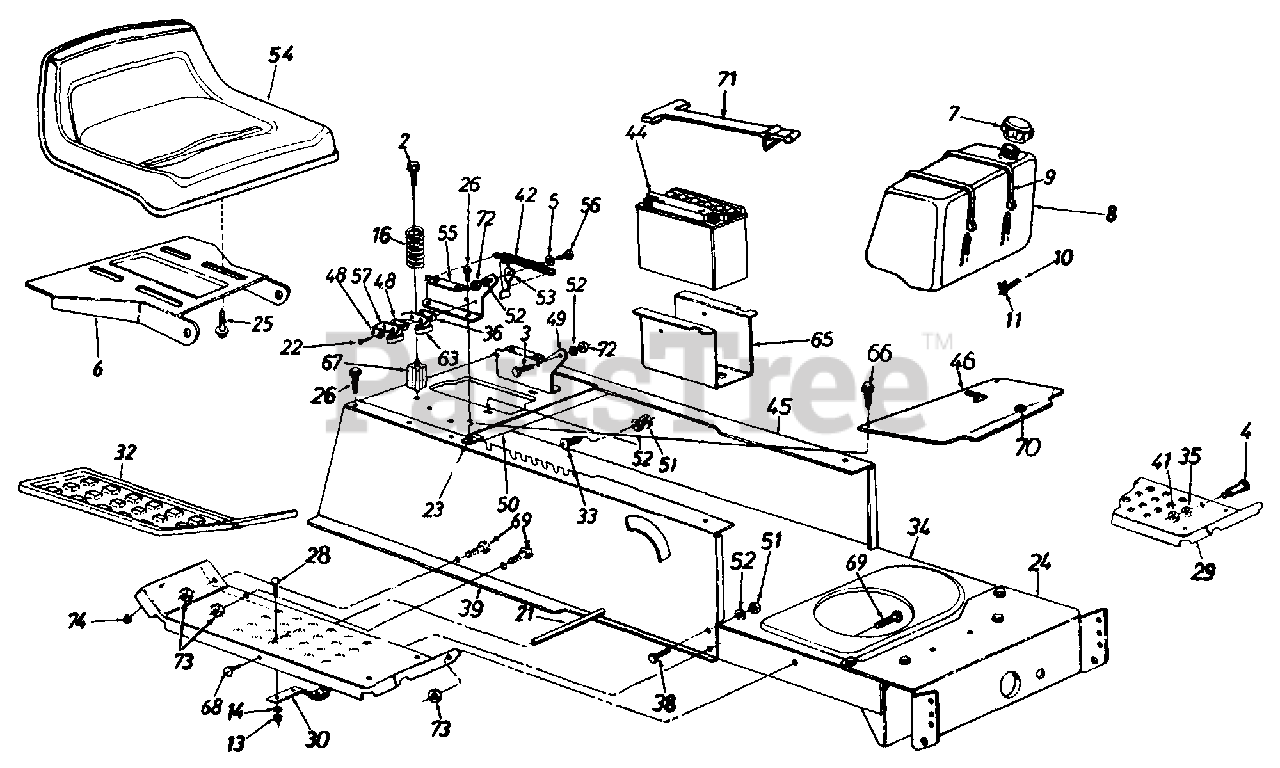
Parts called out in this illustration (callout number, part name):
2	Hex Wash. Hd. Tap Scr. 5/16-18 x 3.25" Lg.
3	Shld. Bolt .437" Dia. x .162"
5	Spr-Wash. .445" I.D. x .75
7	Fuel Cap
9	Tie Strap
10	Fuel Line
13	Hex Nut 1/4-20 Thd.
14	L-Wash. 1/4" I.D.
16	Compression Spring
21	Running Board Rod
22	Hex Hd. AB-Tap Scr. #8 x .50"
23	Speed Nut #10Z
25	Hex Tap Scr. 3/8-16 x .62" Lg.
26	Hex Wash. Hd. AB-Tap Scr. 5/16 x .75" Lg.
32	Rubber Foot Pad - L.H.
33	Truss Mach. Scr. 5/16-18 x .75" Lg.
35	L-Wash. 3/8" I.D.
36	Insulator Boss Plate
38	Hex Bolt 5/16-18 x .75" Lg.
39	Upper Frame - R.H.
41	Hex Nut 3/8-16 Thd.
42	Extension Spring 5.31" Lg.
44	12-V Battery
45	Upper Frame - L.H.
48	Insulator Plate
52	L-Wash. 5/16" I.D.
53	Seat Lift Brkt.
54	Seat
56	Shld. Bolt .437" Dia. x .268"
57	Spring Switch (Seat)
63	Safety Switch (Seat)
66	Truss Mach. B-Tap Scr. #10 x .5"
67	Spring Spacer
68	Pan Hd. Cutting Scr. 5/16-18 x .75" Lg.
69	Hex Bolt 5/16-18 x .75" Lg.
71	Battery Retainer Strap
72	Hex Nut 5/16-18 Thd. (Gr. 5)
73	Hex Sems Nut 5/16-18 Thd.
74	Hex Sems Nut 1/4-20 Thd.
